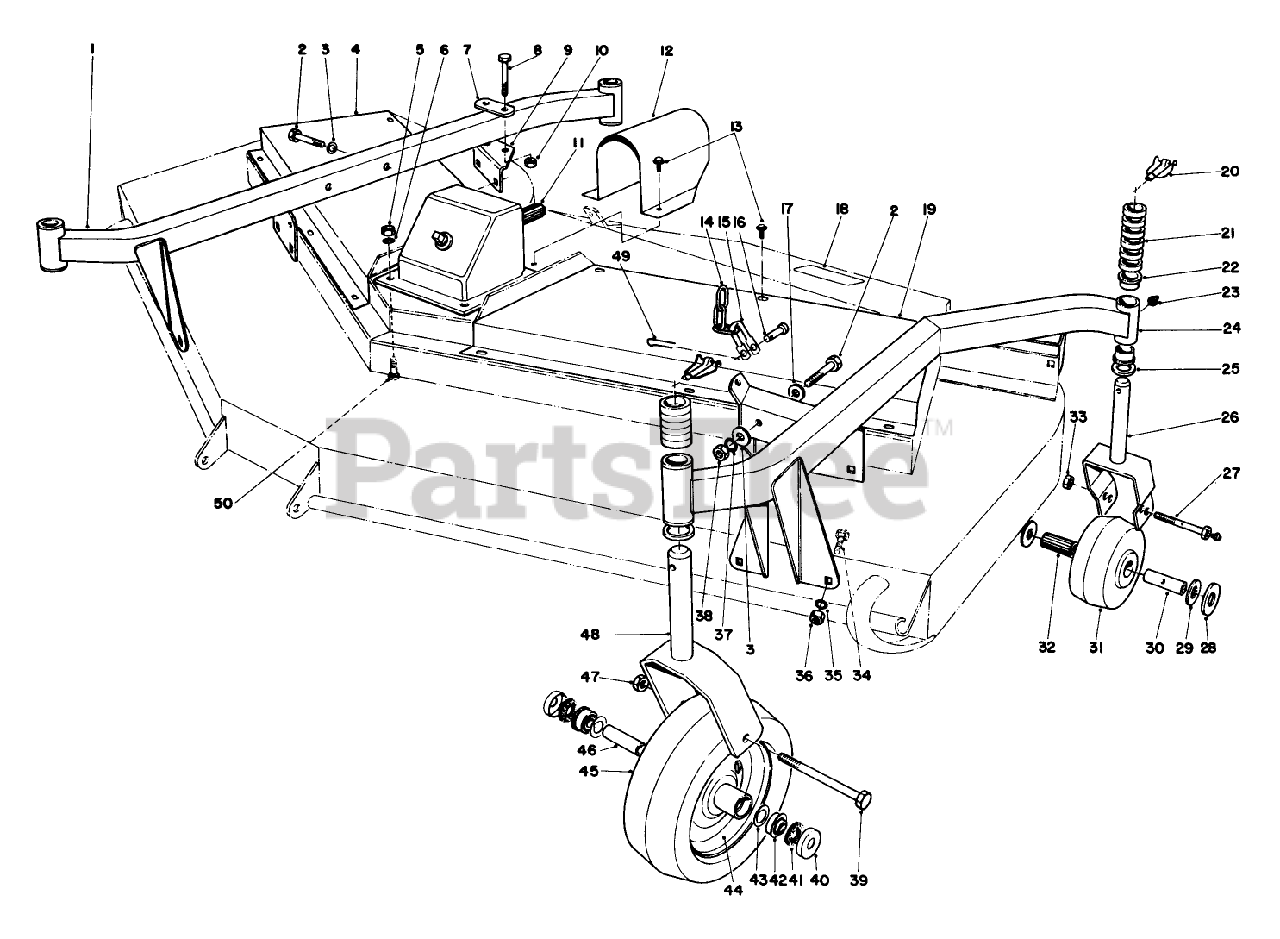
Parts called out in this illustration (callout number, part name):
1	Castor Arm R.H. (Incl. Ref. #22)
2	SCREW-HH
3	WASHER-FLAT
4	RH DECK COVER R
5	NUT-HEX
6	WASHER-LOCK
7	Bar-Caster Clamp
8	SCREW-HH
9	Bracket-Clamp
10	NUT-LOCK, NI
11	GEAR BOX ASM
12	Shroud Universal
13	SCREW-HHF
14	Lift Chain
15	SHACKLE
16	PIN-CLEVIS
17	WASHER-FLAT
18	DECAL-CAUTION, BLADE
19	LH DECK COVER R
20	PIN-LYNCH
21	SPACER 1/2 IN
22	Bushing
23	FITTING-GREASE
24	Castor Arm L.H. (Incl. Ref. #22)
25	WASHER-THRUST
26	Caster Fork Rear
27	AXLE ASM
28	WASHER
29	BEARING RETAINER
30	SPANNER BUSHING
31	WHEEL
32	ROLLER BRG W/46-8960
33	Nut
34	SCREW-CARR
35	WASHER-LOCK
36	NUT-HH
37	WASHER-LOCK
38	NUT-HEX
39	Screw
40	AXLE SLINGER B
41	WASHER
42	.500 RF BALL BEARING
43	WASHER
44	Castor Wheel (Incl. Ref. #45)
46	SPACER
47	NUT-HEX
48	Caster Fork
49	PIN-COTTER
50	SCREW-CARR
